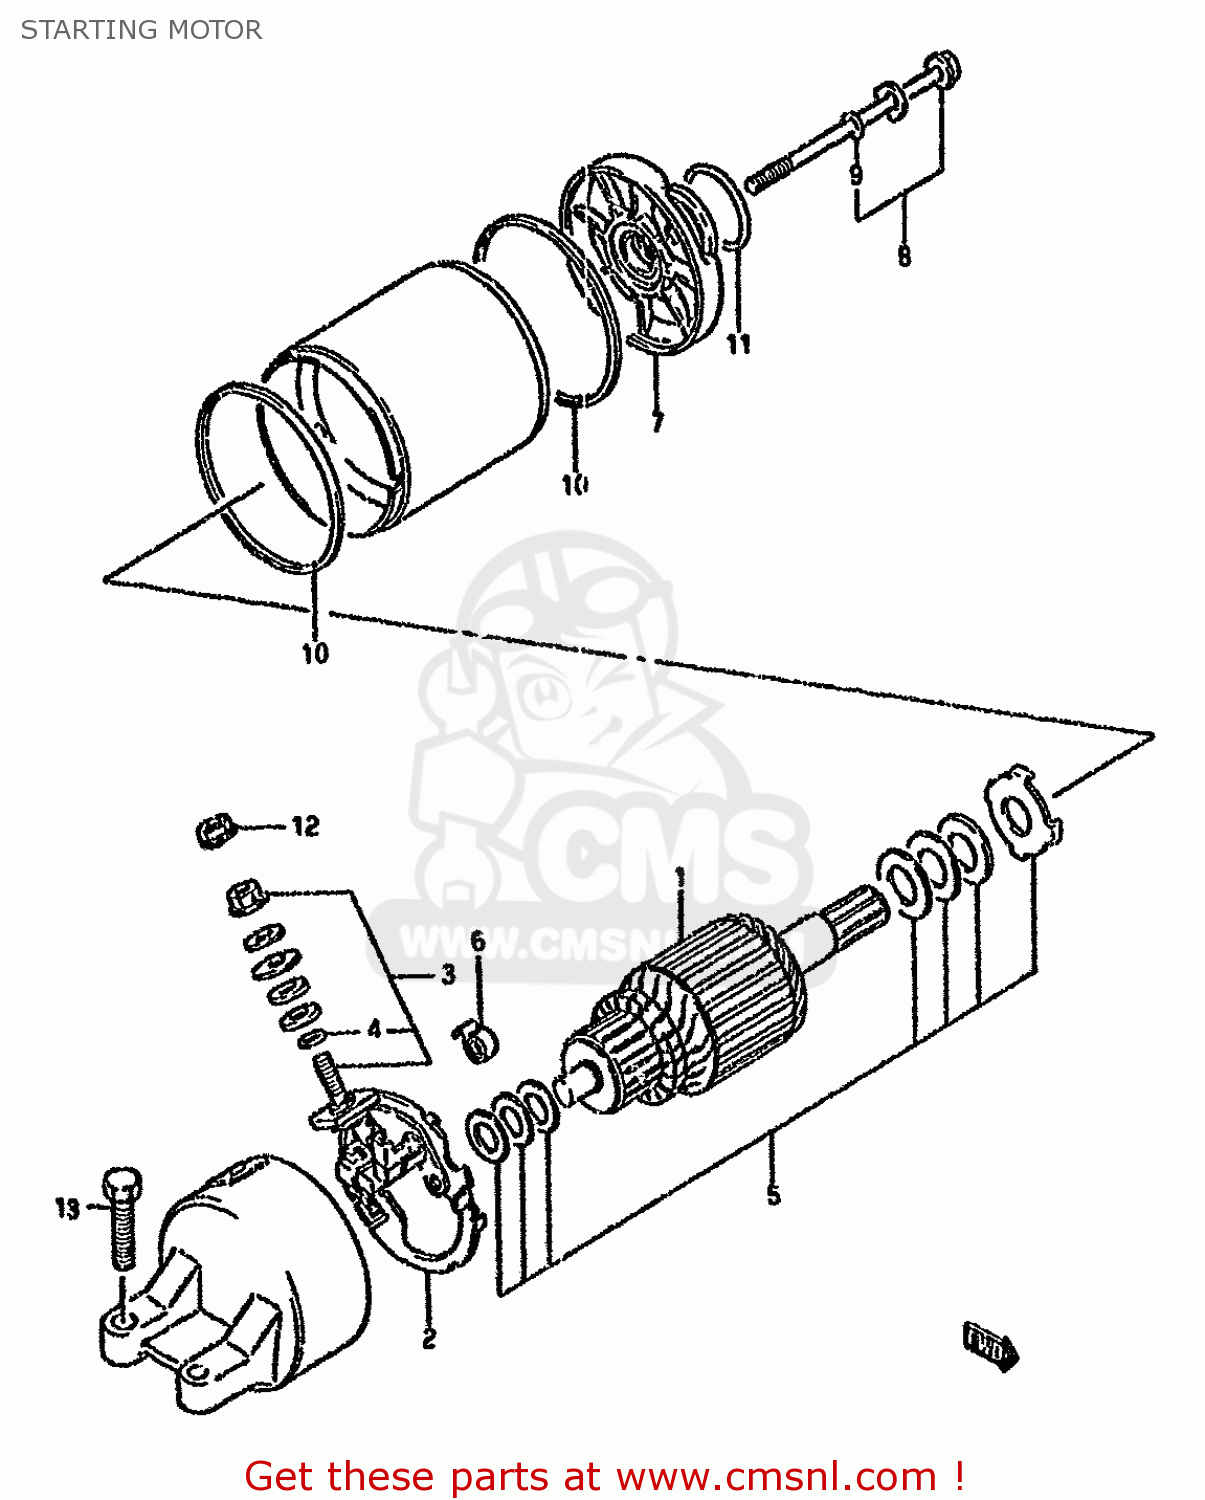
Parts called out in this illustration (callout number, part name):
1	ARMATURE
2	HOLDER SET,BRUSH
3	TERMINAL SET,BRUSH,PLUS
4	O RING
5	SHIM SET,STARTING MOTOR
6	SPRING,BRUSH
7	BRACKET ASSY,FR
8	BOLT SET,STARTING MOTOR
9	O RING
10	O RING
11	O RING(D:3,ID:24.5)
12	NUT
13	SCREW (6X25)
